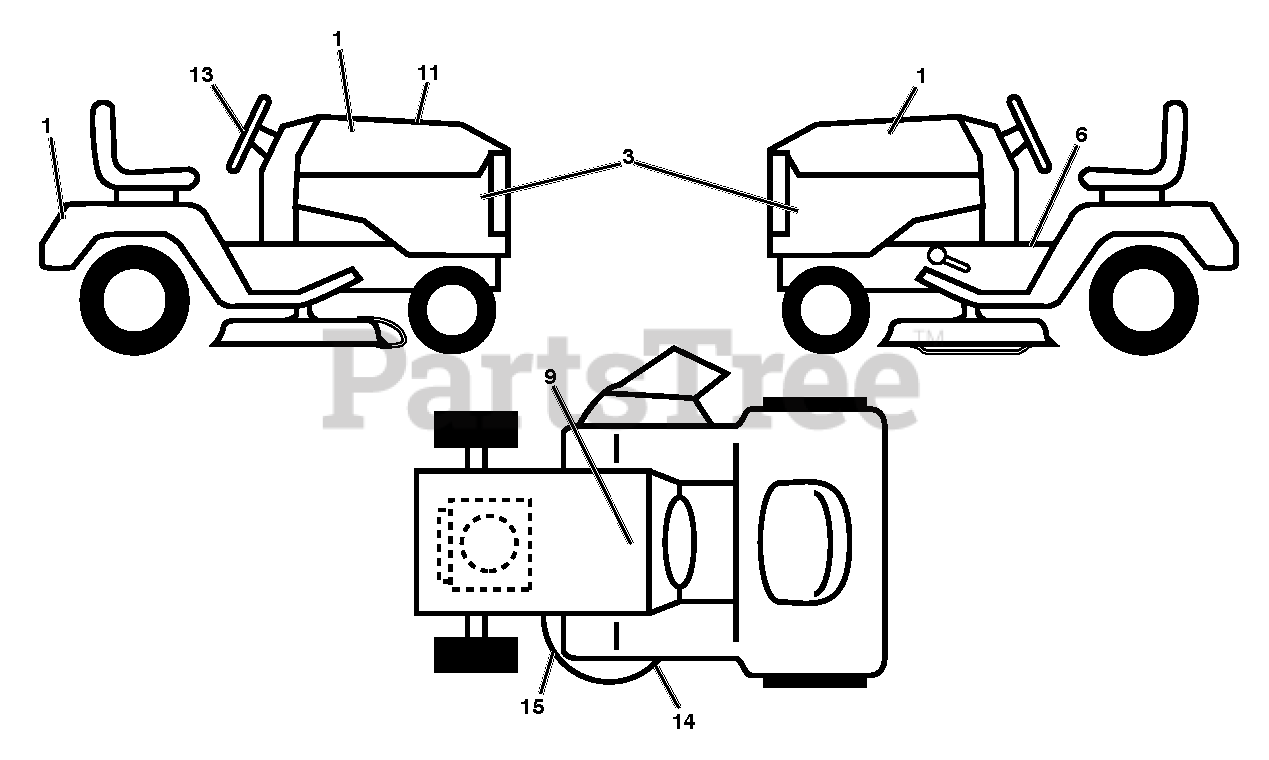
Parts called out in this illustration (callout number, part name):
1	DECAL, DIXON LOGO, DOMED
6	DECAL.WARN.STARTINST.
9	DECAL BTRY SYMBOLS
11	DECAL.RPL
13	DECAL.WHEEL.STEER.DIXON
14	DECAL.MOWER.SCH.48/54
15	DECAL.MOWER
